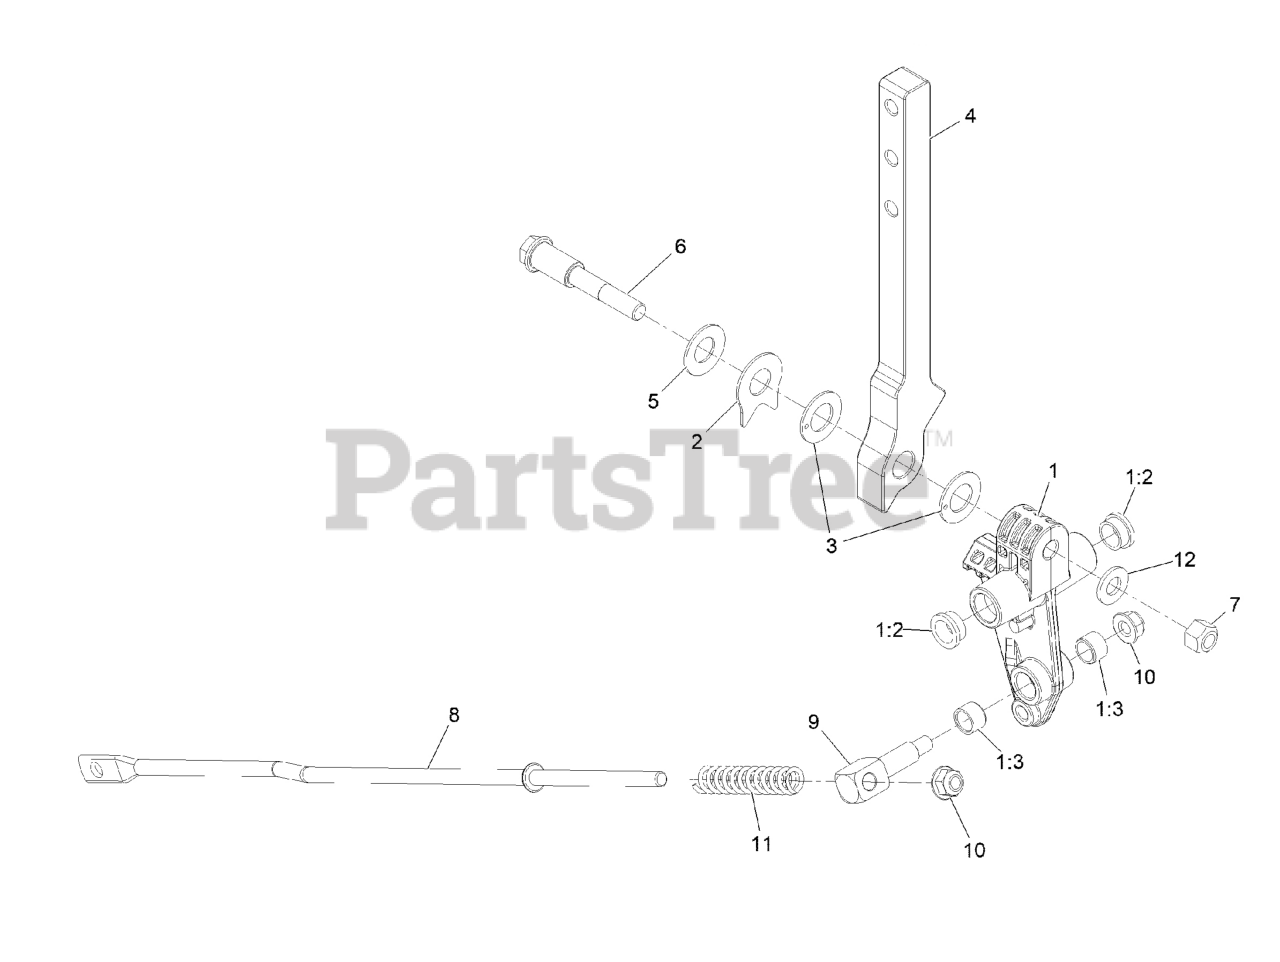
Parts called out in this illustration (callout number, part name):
1	CONTROL ARM ASM
1:2	BUSHING
1:3	BUSHING-SLEEVE
2	Spacer, Anti-Rotation
3	WASHER-FRICTION
4	Lever, Motion Control
5	WASHER-BELLEVILLE
6	Bolt-Pivot
7	NUT-LOCK, CONE
8	LINK-CONTROL
10	NUT-HF, NI
11	SPRING-RETURN, NEUTRAL
12	WASHER-FLAT
